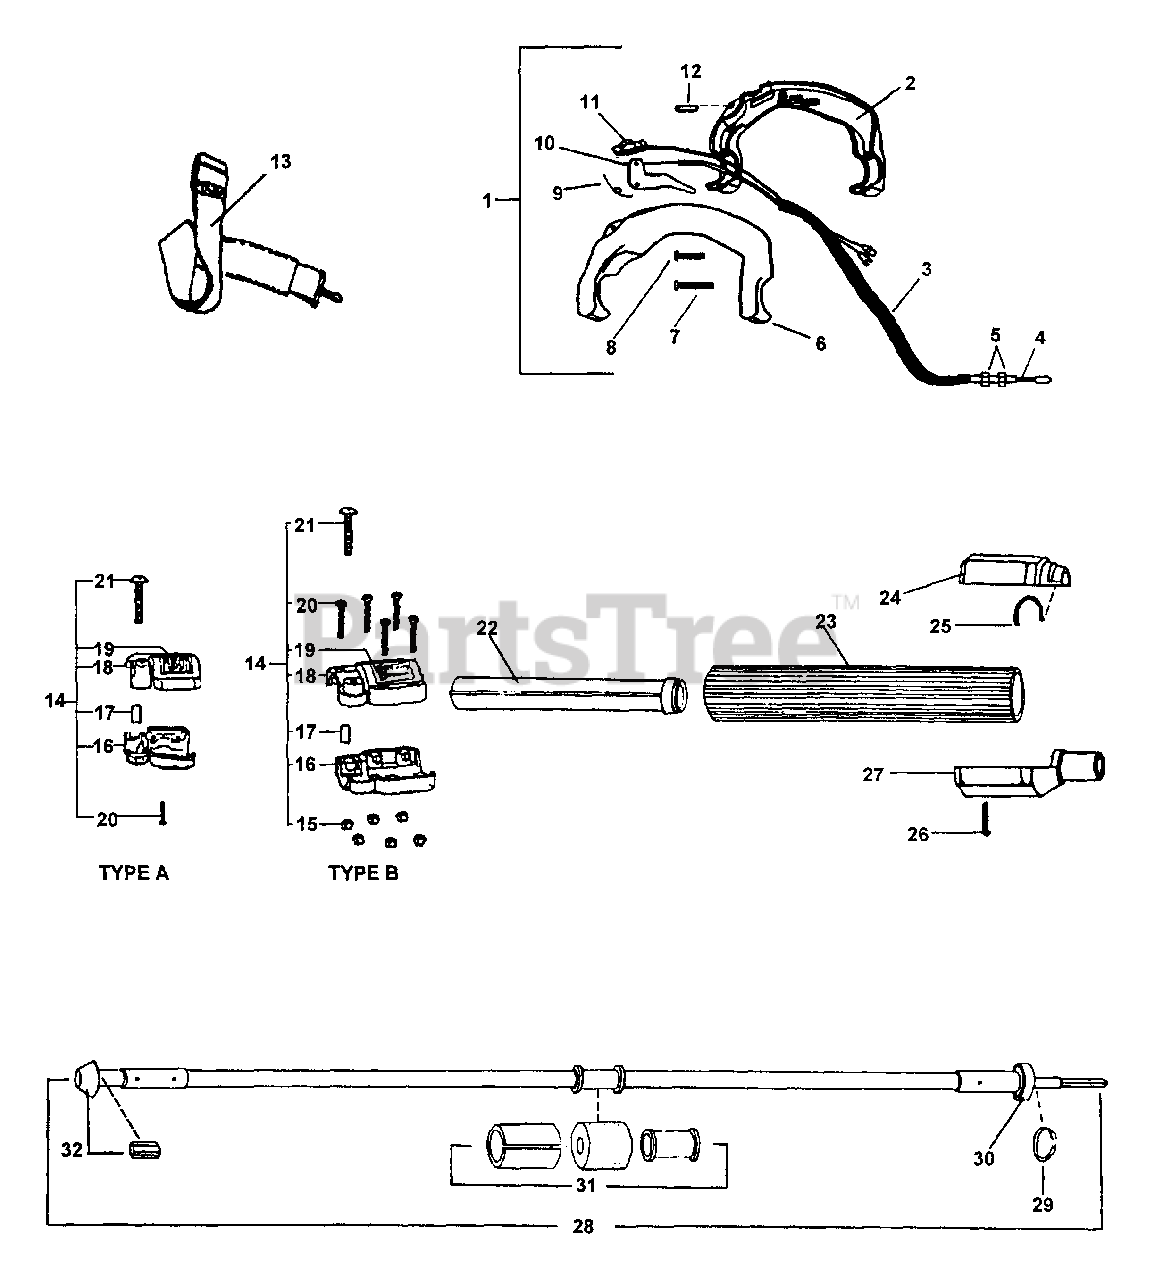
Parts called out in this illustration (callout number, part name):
1	HANDLE ASSY, REAR
2	HANDLE, REAR - RIGHT
3	TUBE, FLEXIBLE
4	CABLE, THROTTLE
6	HANDLE, REAR - LEFT
7	SCREW, TORX 10-24 UNC 1-1/4
8	SCREW, TORX
9	SPRING, TORSION
10	TRIGGER, THROTTLE
11	IGNITION SWITCH ASSY
12	PIN, LOCATING 0.17 OD×0.75 L
13	STRAP ASSY, SHOULDER
14	COLLAR, MAIN PIPE
15	NUT, LOCK 10-24 UNC
16	COLLAR, LOWER
17	SLEEVE, HEAD LOCATING
18	COLLAR, UPPER
19	LABEL - CAUTION
20	SCREW, TORX 10-24 UNC 1-1/4
22	PIPE, MAIN
23	PIPE, MAIN
24	CAP, MAIN PIPE
26	SCREW, TORX 10-24 UNC 1-1/4
27	COUPLING, MAIN PIPE
28	DRIVESHAFT ASSY
29	RING, RETAINING
30	BEARING, BALL 6002 DDU
31	DRIVESHAFT GUIDE ASSY
32	ADAPTER, UPPER DRIVE SHAFT
